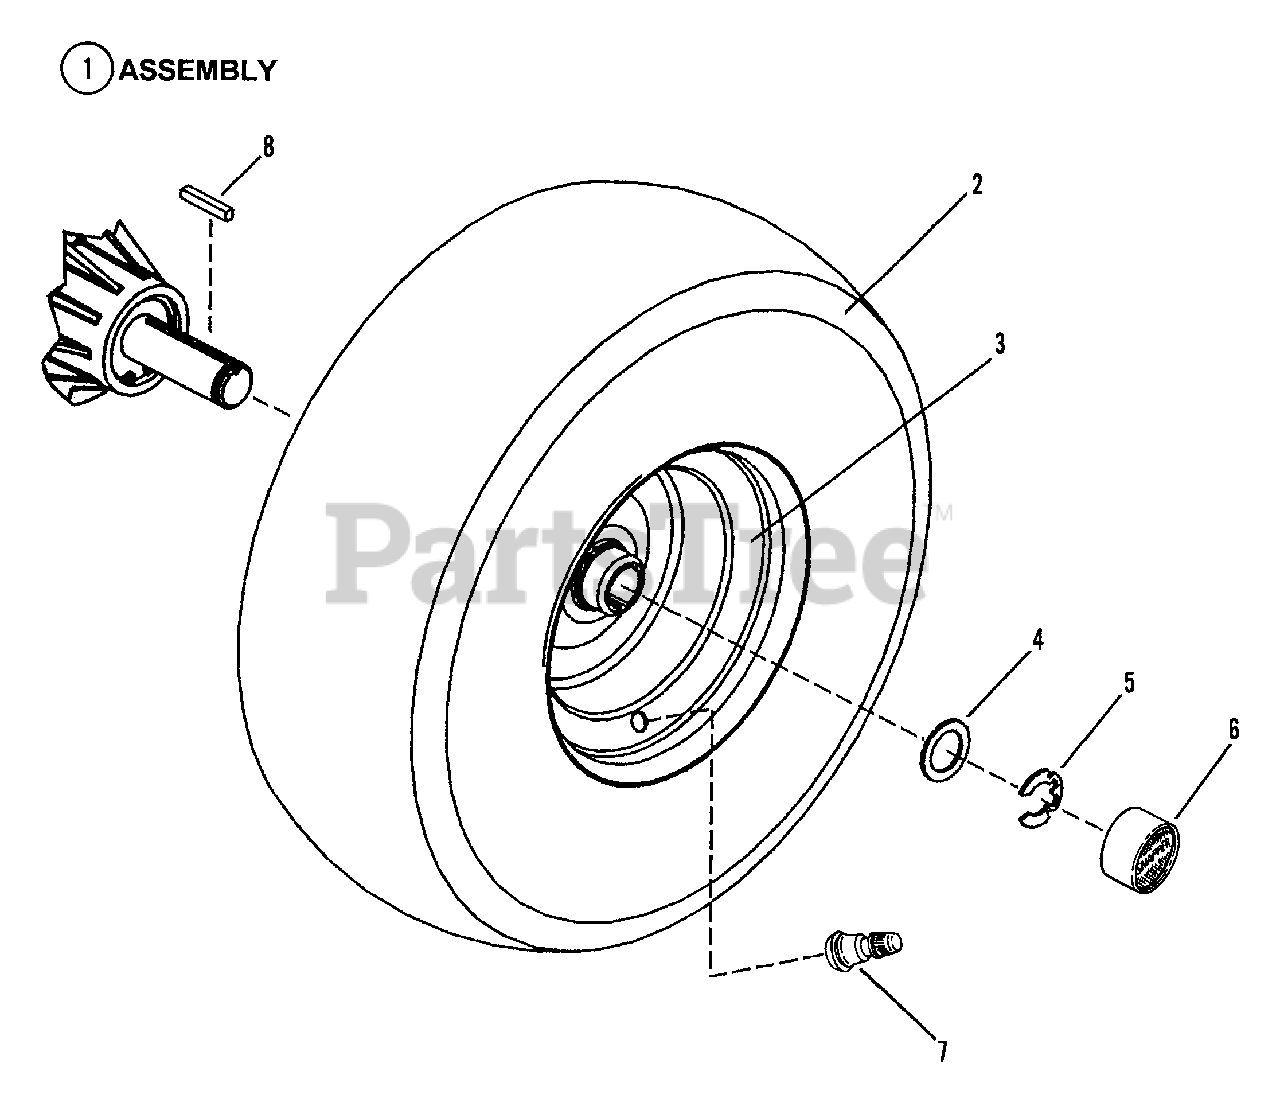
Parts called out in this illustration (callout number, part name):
1	ASSEMBLY, Rear Tire & Rim 18x7.00-8 (33" Models)
2	TIRE, 18 x 6.50-8, Smooth Tread (33" Models)
2	TIRE, 18 x 8.50-8, Smooth Tread (38" & 42" Models)
3	RIM, 18 x 6.50 (33" Models)
3	RIM, 18 x 8.50 (38" & 42" Models)
4	BUSHING, Machine
5	RING, Retaining, External 1"
6	CAP, Hub
7	STEM, Valve
8	KEY, Square M6 x 38
